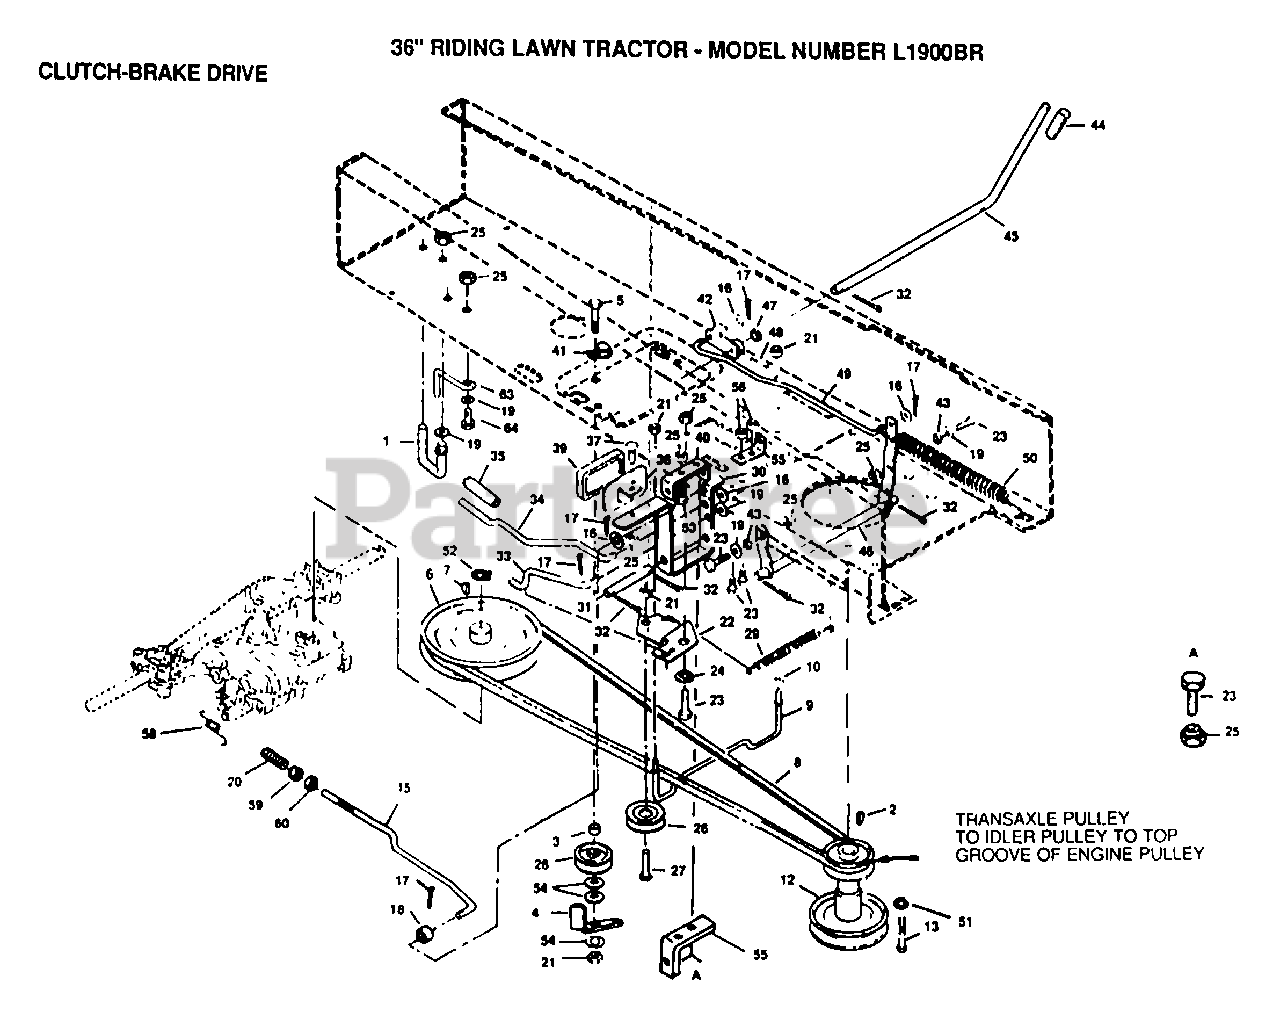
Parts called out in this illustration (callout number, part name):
1	BELT GUIDE T
4	BELT KEEPER T
6	PULLEY-TRANS T
9	MID BELT GUIDE LT
10	WASHER
13	BOLT RER
16	WASHER
18	WASHER
19	WASHER M
20	SPRING ROD LT
22	IDLER BRACKET
23	BOLT
29	IDLER SPRING
30	FOOT PEDAL LT
32	PIN COTTER 1/8
34	PARK BRK ROD T
36	PEDAL PLATE LT
37	BOLT
39	FOOT PAD LT
40	PEDAL BRACKET T
45	CLUTCH HANDLE L
49	BALDE ROD LT
51	LOCKWASHER
53	BOLT
54	WASHER
55	SWITCH BRKT
60	NUT
63	BELT RETAINER GT
